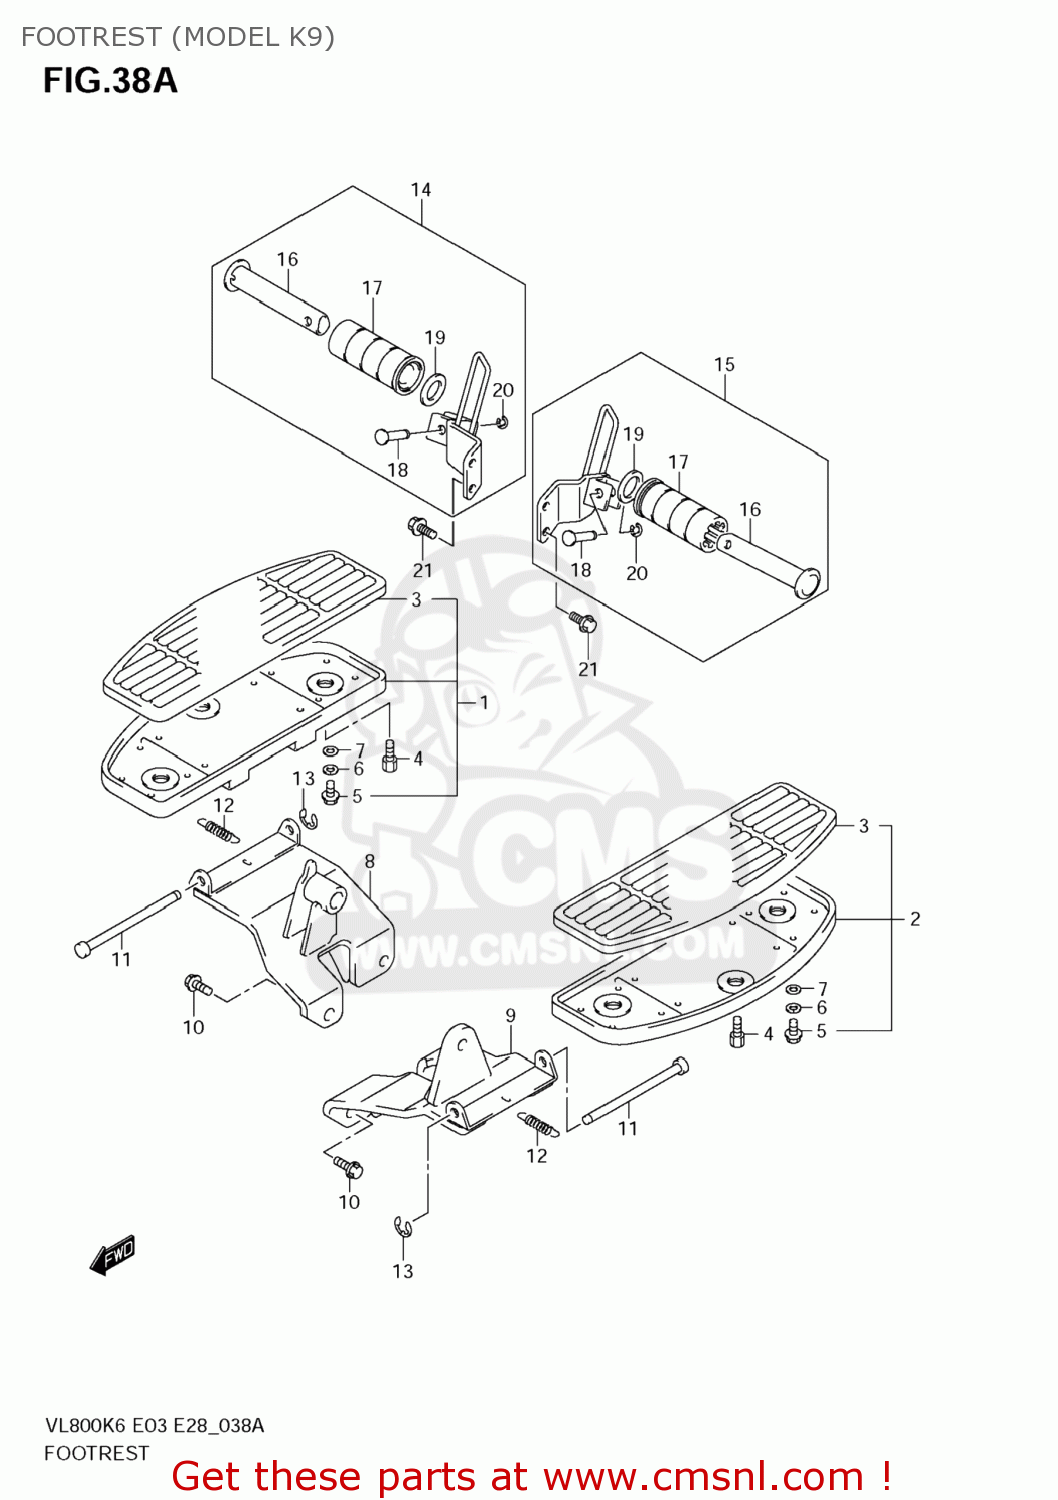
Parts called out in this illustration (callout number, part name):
1	FOOTREST ASSY,
2	FOOTREST ASSY,
3	RUBBER,FR FOOTREST
4	BOLT,BANK SENSOR
5	BOLT
6	WASHER(6.5X22X1.6)
7	CUSHION
8	BRACKET,FR FOOTREST,R
9	BRACKET,FR FOOTREST,L
10	BOLT
11	PIN,FR FOOTREST
12	SPRING
13	E RING
14	FOOTREST ASSY,PILLION,R
15	FOOTREST ASSY,PILLION,L
16	BAR,PILLION FOOTREST
17	RUBBER,PILLION FOOTREST
18	PIN,PILLION FOOTREST
19	WASHER(19.5X32X2)
20	E RING
21	BOLT(8X16)
